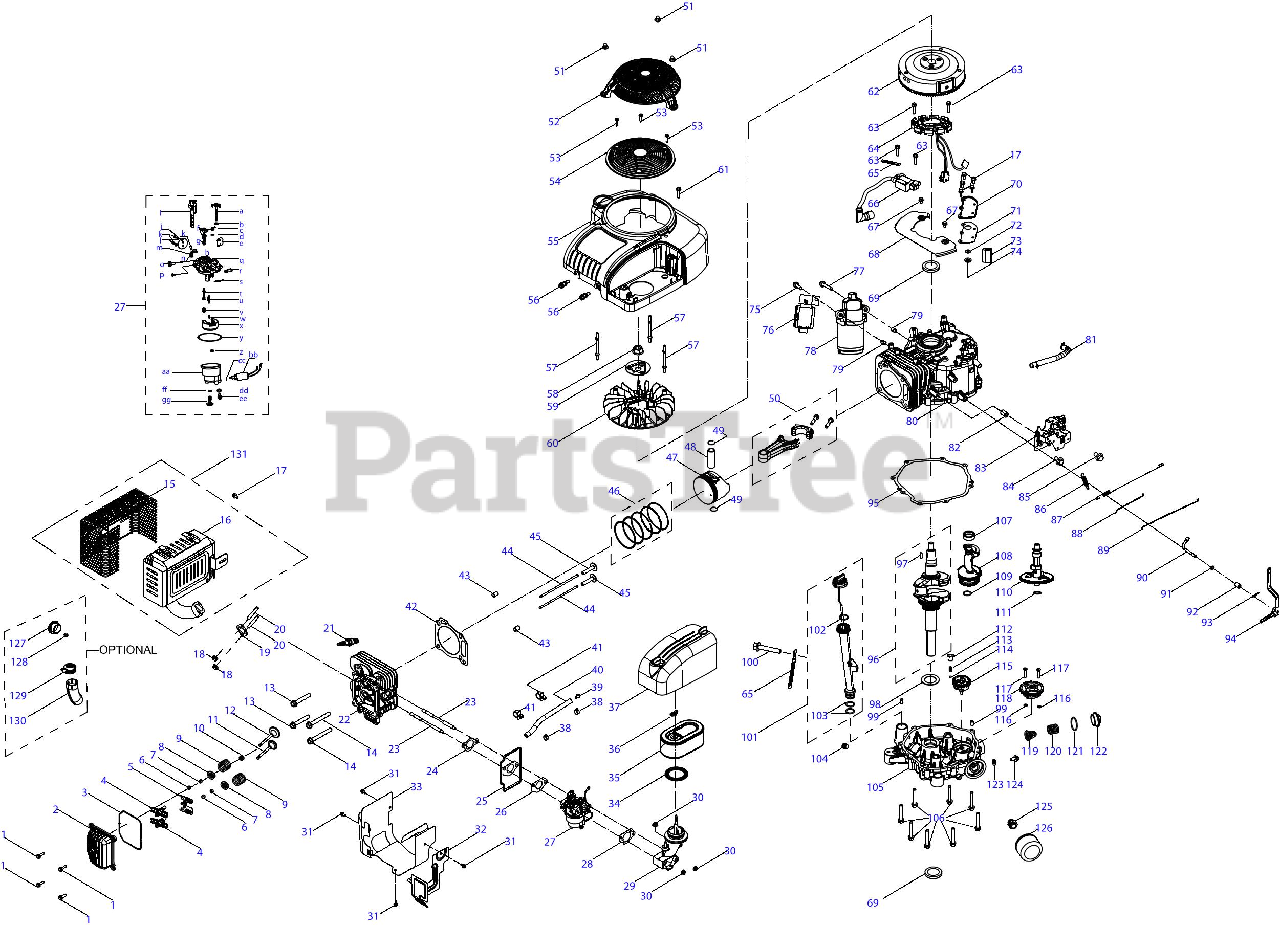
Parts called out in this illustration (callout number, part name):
1	Bolt, M6x22
2	Valve Cover
3	Gasket, Valve Cover
4	Rocker Arm Assembly
5	Rocker Arm Base
6	Valve Adjust Cap, Exhaust
7	Valve Locker
8	Valve Spring Seat
9	Valve Spring
10	Intake Valve Seal
11	Exhaust Valve
12	Intake Vavle
13	Bolt, M10x1.25x65
14	Bolt, M10x1.25x87
15	Muffler Guard
17	Bolt, M6x14
19	Gasket, Muffler
20	Stud, M8x47
21	Spark Plug
22	Cylinder Head
23	Stud, M6-8x140
24	Gasket, Carburetor Insulator
26	Gasket, Carburetor
27	Carburetor
28	Gasket, Intake Manifold
29	Intake Manifold
31	Bolt, M5x10
34	Ring,Air Filter
35	Air Filter Assembly
36	Butterfly Nut
37	Air Filter Cover Assembly
38	Clamp
40	Fuel Hose, 6.3x12.5x290
41	Clip
42	Gasket, Cylinder Head
43	Pin, 12x16
44	Push Rod
45	Tappet
46	Piston Ring Set
48	Piston Pin
49	Circlip
50	Connecting Rod Assembly
51	Nut, M6
53	Self-tappling Screw, ST5.5x25
57	Stud, M6x99
58	Nut, M16x1.5
59	Cooling Fan Plate
60	Cooling Fan
61	Bolt, M6x16
63	Bolt, M6x28
64	Charging Coil
65	Clip
66	Ignition Module
67	Bolt, M6x10
69	Oil Seal, 35x52x7
70	Breather Cover
71	Gasket, Breather Cover
72	Breather Valve
73	Breather Filter Screen
74	Second Air Valve Seat
75	Bolt, M8x40
76	Regulator Assembly
77	Stud, M8-6x58
78	Electric Starter
81	Breather Hose
82	Bush, 6.5x15x20
83	Governor Gear Bracket Assembly
84	Bolt, M6x38
85	Bolt, M6x18
86	Governor Spring
87	Idle Spring
88	Choke Lever
89	Throttle Linkage
90	Governor Gear Shaft
91	Washer, 6x1x12
92	Oil Seal, 6x11x4
93	Cotter Pin
94	Governor Lever
95	Gasket, Crankcase
96	Crankshaft
97	Woodruff Key
98	Washer, 35.4x2x54
100	Bolt, M6x35
102	O-Ring, 21.9x2.62
103	O-Ring, 21.2x2.8
104	Earth Bolt
105	Crankcase Cover
106	Bolt, M8x54
107	Bearing, 6202
108	Balance Shaft
109	Washer, 15.4x1x25
111	Washer, 16.4x1x24
114	Steel Ball, S6.35
115	Governor Gear
116	O-Ring, 10x2.65
119	Breather Filter Screen
120	Breather Spring
121	O-Ring, 35.5x2.65
122	Breather Cover
123	Washer, 8.3x1.5x17
124	Bolt, M8x15
125	Connection Pipe
126	Oil Filter
127	Spark Arrester
128	Self-tappling Screw, ST5x8
130	Pipe Oriented
